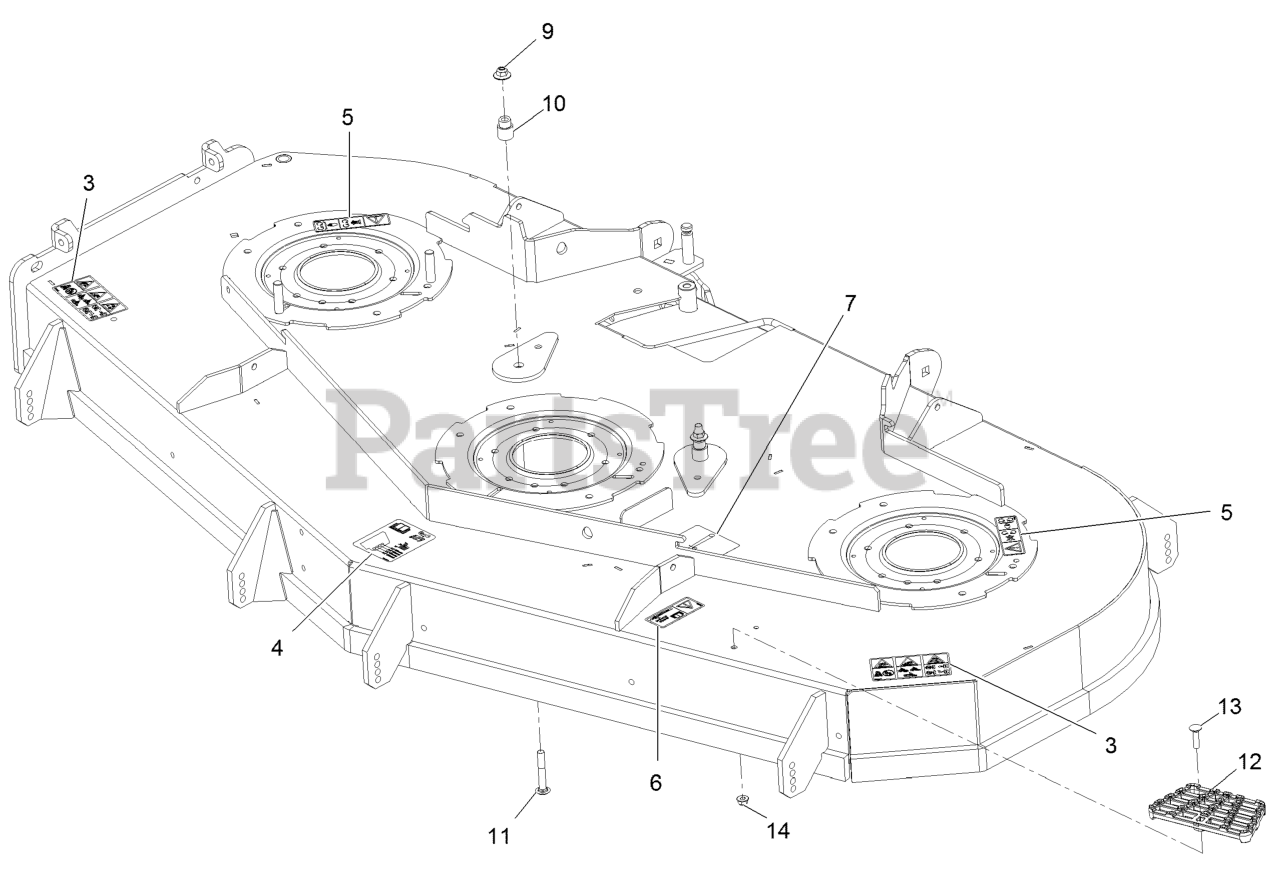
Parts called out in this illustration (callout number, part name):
3	Decal-Danger Thrown Objects
4	Decal-Roller, Anti-Scalp
5	Decal-Missing, Cover
6	Decal-Bolt Torque
7	Decal-Belt Routing
9	Nut-Flange, NI
10	Bushing, Idler
11	Screw-CARR
12	Step-Deck
13	Screw-CARR
14	Nut-Flange, NI
